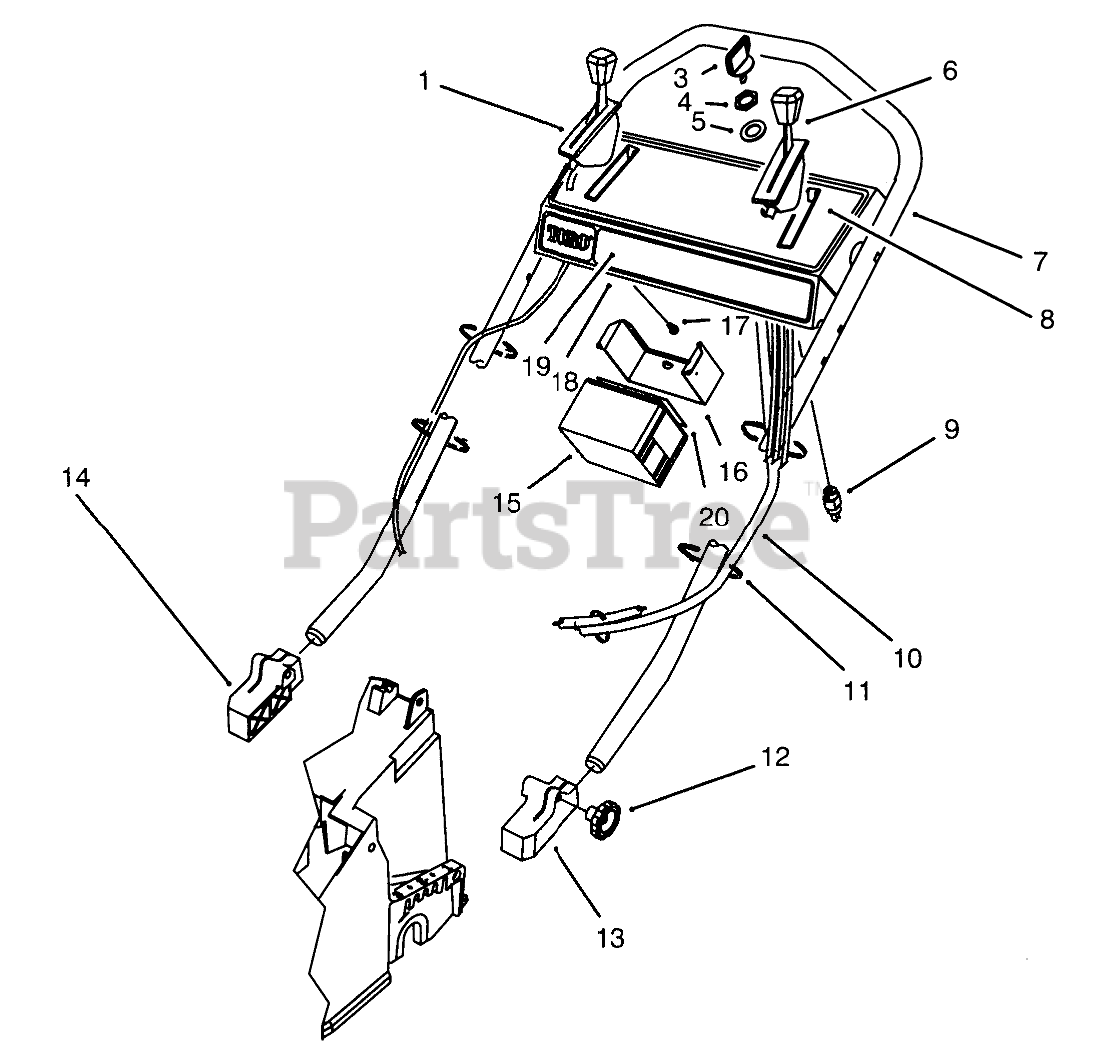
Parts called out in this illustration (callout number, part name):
1	CONTROL-SPEED, GROUND
3	KEY-IGNITION
4	NUT-HH
5	WASHER-TOOTH, INTERNAL
6	CONTROL - THROTTLE
7	HANDLE - 53CM (DIPPED)
8	DECAL - INSTRUCTION
9	Switch-Starter (Incl. Ref. #4 & 5)
10	Harness-Wire
11	TIE-CABLE
13	MOUNT-HANDLE, LH
14	MOUNT-HANDLE, RH
15	BATTERY ASSEMBLY
16	Retainer-Battery
17	SCREW-TAP
18	Panel-Control (Incl. Ref. #8 & 19)
19	DECAL - PANEL KEY
20	DECAL-BATTERY
